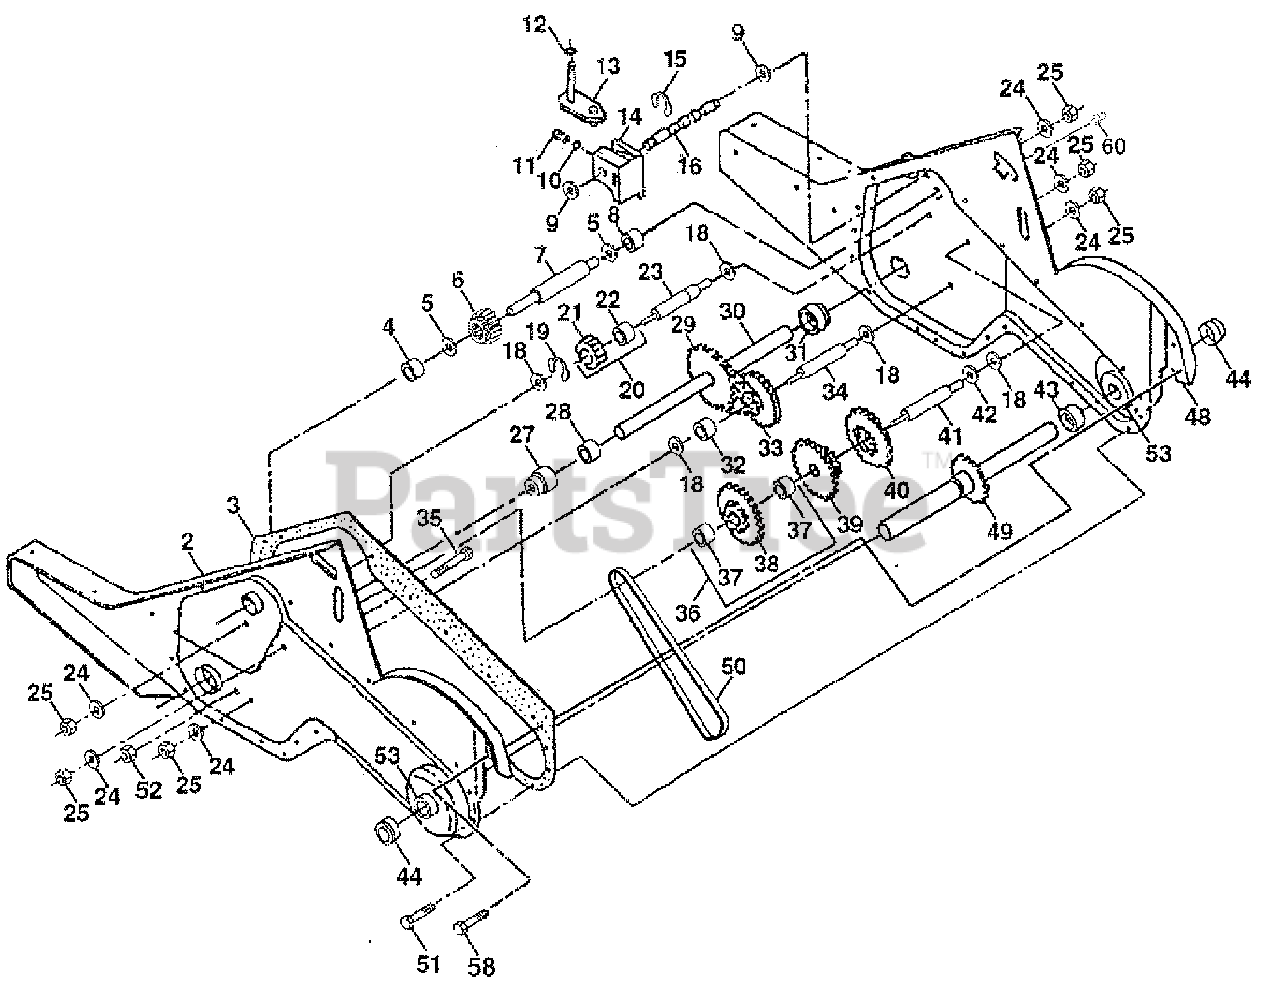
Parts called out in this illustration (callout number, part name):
1	Transmission Assembly
2	Gearcase, L.H. w/Bearing
3	Gasket, Gearcase
4	Bearing, Needle
5	Washer, Thrust 5/8 x 1.10 x 1/32
6	Pinion, Input
7	Shaft, Input
8	Bearing, Needle
9	Washer, Seal
10	Ball, Steel
11	Spring, Shift, Fork
12	O-Ring
13	Arm,. Shift
14	Fork, Shift
15	Ring, Klip
16	Shaft, Shift
18	Washer
19	Ring, Klip
20	Gear, Assembly, Reverse Idler
21	Gear, Reverse Idler
22	Bearing, Needle
23	Shaft, Reverse Idler
24	Washer, Lock 7/16
25	Nut, Hex 7/16-20
27	Bearing, Shaft, Ground Drive L.H.
28	Spacer 0.765 x 1.125 x 1.23
29	Chain #35-50 Pitch
30	Ground Shaft Assembly
31	Bearing, Shaft, Ground Drive R.H.
32	Spacer 0.70 x 1.00 x 1.150
33	Sprocket and Gear Assembly
34	Shaft, Reduction (2nd)
35	Screw, Whiz, Lock 5/16-18x3-1/2
36	Sprocket Assembly w/Bearing
37	Bearing, Needle
38	Sprocket, Tine
39	Gear, Cluster, Red 1st & 2nd
40	Gear, Reverse
41	Shaft, Reduction (1st)
42	Washer, Thrust
43	Spacer 1.01 x 1.75x0.760
44	Seal Asm. Oil
48	Gearcase, R.H. w/Bearing
49	Shaft, Tine
50	Chain, Roller #50-50 Pitch
51	Screw 1/4-20 x 1/2
52	Nut, Hex 5/16-18
53	Kit, Bearing, Tine Shaft
58	Screw 1/4-20 x 3/4
60	Fitting Grease
60	Grease, Plastilube #1
